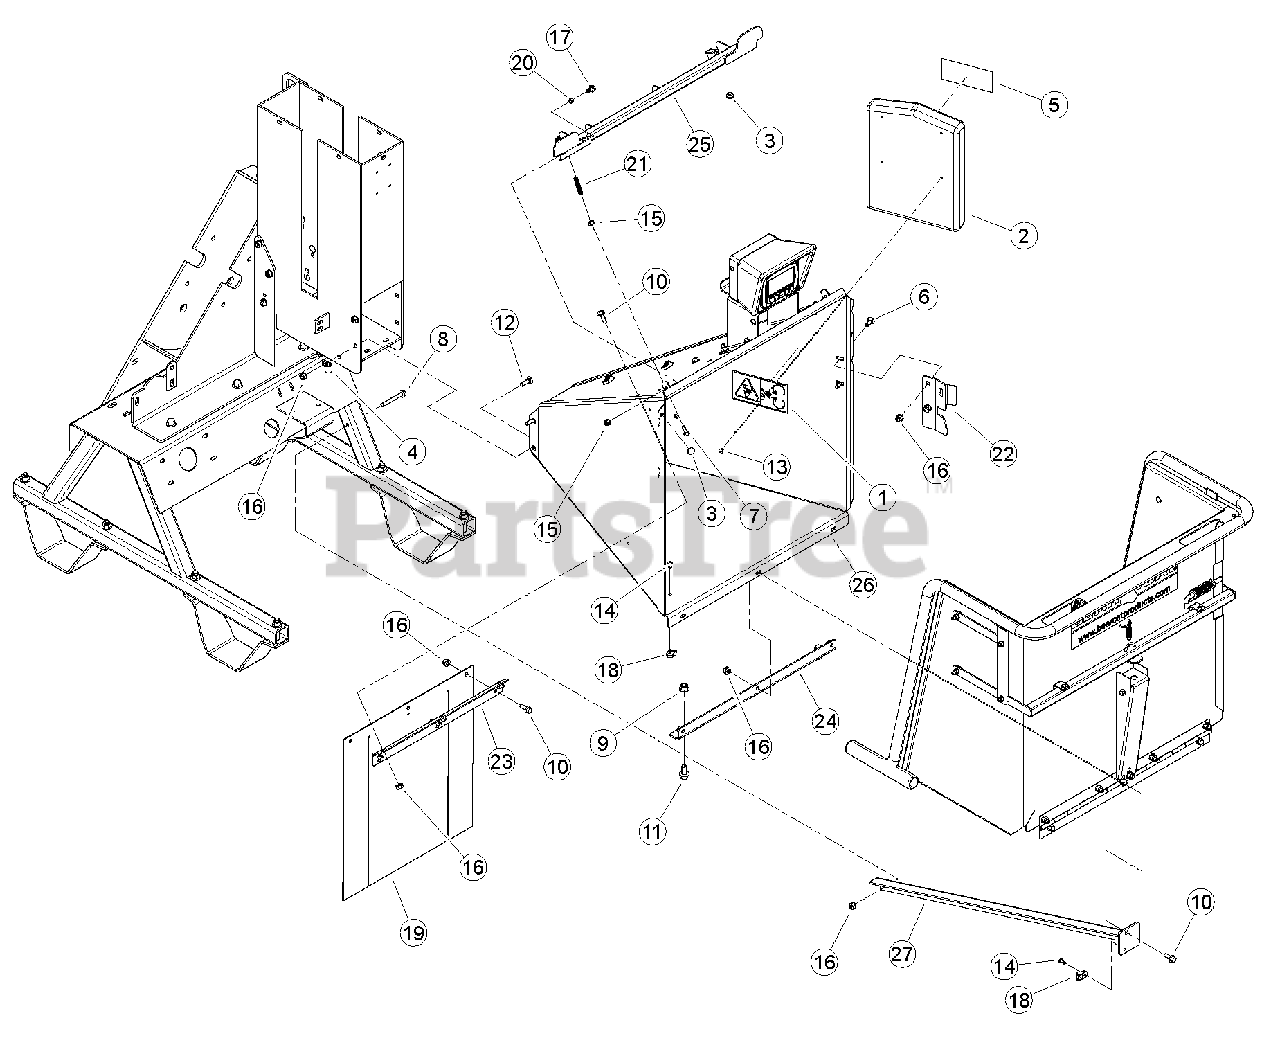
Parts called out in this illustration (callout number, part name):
1	DECAL, BLADE DANGER ISO
2	CONTAINER, INSTR. MANUAL
3	BUMPER, RUBBER
4	CLAMP, 9/16 COATED
5	DECAL, MULTILINGUAL MANUAL
6	BOLT, 3/8-16 X 1 GR5 CRG
7	BOLT, 5/16 X 3/4 FLANGE NC
8	BOLT, 3/8 X 3 FLANGE NC
9	NUT, 1/2-13 NYLOCK FLANGE
10	BOLT, 3/8 X 1 FLANGE NC
11	BOLT, 1/2-13 1.00 GR5 FLANGE NC
12	BOLT, 3/8-16 X 1-1/4 GR5 CRG
13	RIVET, AL BLIND 1/4 X 1/2 DOME HEAD
14	RIVET, AL BLIND 1/4 X 3/4 DOME HEAD
15	NUT, 5/16-18 NYLOCK FLANGE
16	NUT, 3/8-16 NYLOCK FLANGE
17	BOLT, 5/16-18 X 3/4 ZP FLANGE SHOULDER
18	CLAMP, CABLE MOUNT
19	FLAP, 5 INCH CHUTE
20	BEARING, .375 X .50 X .25 LONG
21	SPRING, COMPRESSION .437 DIA X 2.0 LONG
22	PLATE, TRAY LATCH
23	SUPPORT, 5 INCH CHIPPER FLAP
24	ANGLE, 5" INFEED SUPPORT
25	WELDMENT, 5" TOP SAFETY BAR
26	WELDMENT, 5" CHIPPER CHUTE
27	WELDMENT, CHUTE SUPPORT
